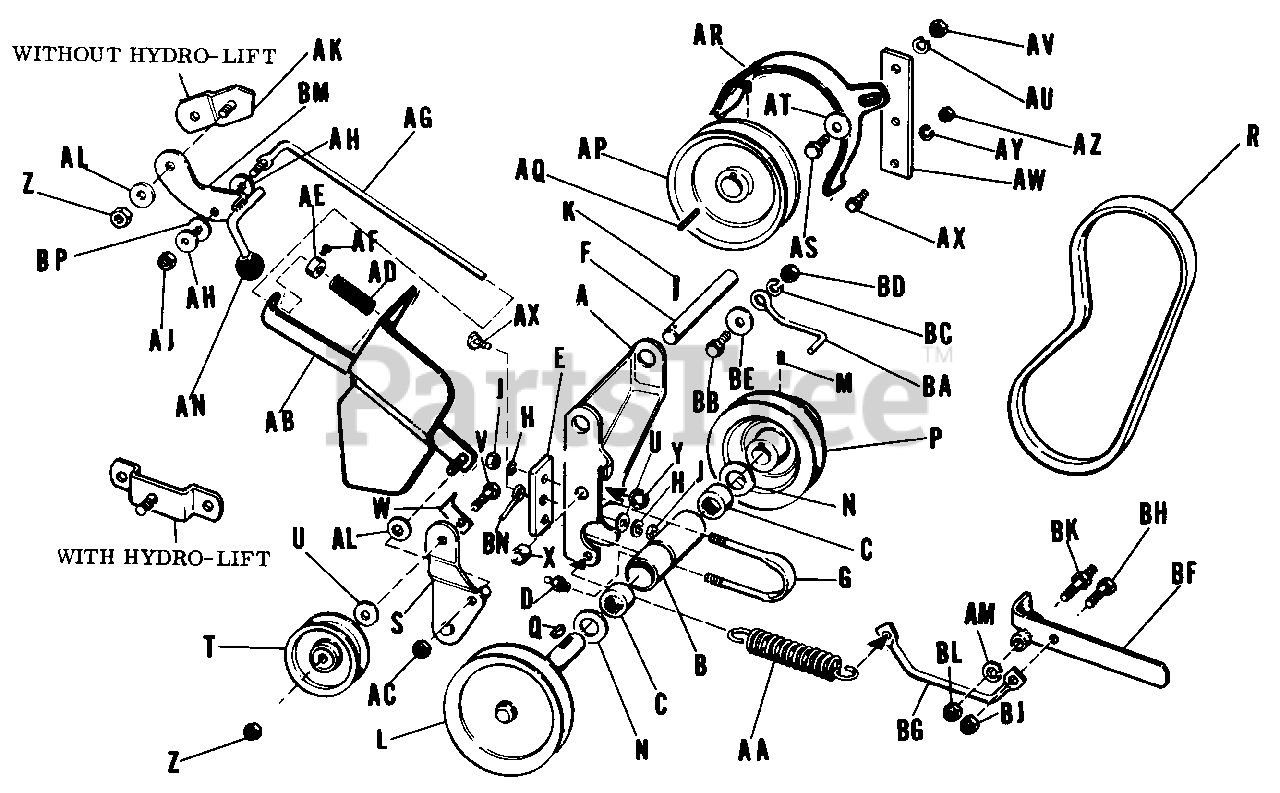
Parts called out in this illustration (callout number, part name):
A	P.T.O.-Bracket
B	Bearing Housing
C	Needle Bearing
D	Grease Fitting
E	Support Plate
F	Pivot Rod, 5/8" Dia. x 6-13/16"
H	Lock Washer, 5/16"
J	Full Hex. Nut, 5/16"-18
K	Cotter Pin, 3/16" Dia. x 1-1/2"
L	Shaft Assembly, P.T.O.
M	Set Screw, 5/16"-18 x 5/16"
P	P.T.O. Pulley
Q	Woddruff Key #9-3/16" x 3/4"
S	Idler Lever Assembly
T	Idler Pulley
U	Plain Washer, 5/16"
V	Hex. Cap Screw, 3/8"-16 x 1-1/4"
Y	Retaining Ring
Z	Full Hex. Nut, 3/8"-16
AA	Tension Spring
AB	Rod Guide Assembly
AC	Full Lock Hex. Nut, 3/8"-16
AF	Set Screw, 1/4"-20 x 3/8"
AG	Clutch Rod Assembly
AH	Plain Washer, 5/16"
AJ	Full Lock Hex. Nut, 5/16"-18
AK	Pivot Bar Assembly
AL	Plain Washer, 3/8"
AM	Lock Washer 7/16"
AR	Belt Guard Assembly
AS	Hex. Cap Screw, 3/8"-16 x 1"
AT	Plain Washer, 3/8"
AU	Lock Washer, 3/8"
AV	Full Hex. Nut, 3/8"-16
AW	Belt Guard Support
AX	Hex. Cap Screw, 5/16"-18 x 1"
AY	Lock Washer, 5/16"
AZ	Full Hex. Nut, 5/16"-18
BB	Hex. Cap Screw. 5/16-18 x 1"
BC	Lock Washer, 5/16"
BD	Full Hex. Nut, 5/16-18
BE	Plain Washer, 5/16"
BF	Handle Assembly
BG	Spring Tension Rod
BH	Hex. CapScrew, 5/16"-18 x 3/4"
BJ	Full Lock Hex. Nut, 5/16"-18
BL	Full Lock Hex. Nut, 7/16"-14
BM	Clutch Lever Assembly
BN	Belt Guide
BP	Special Washer
